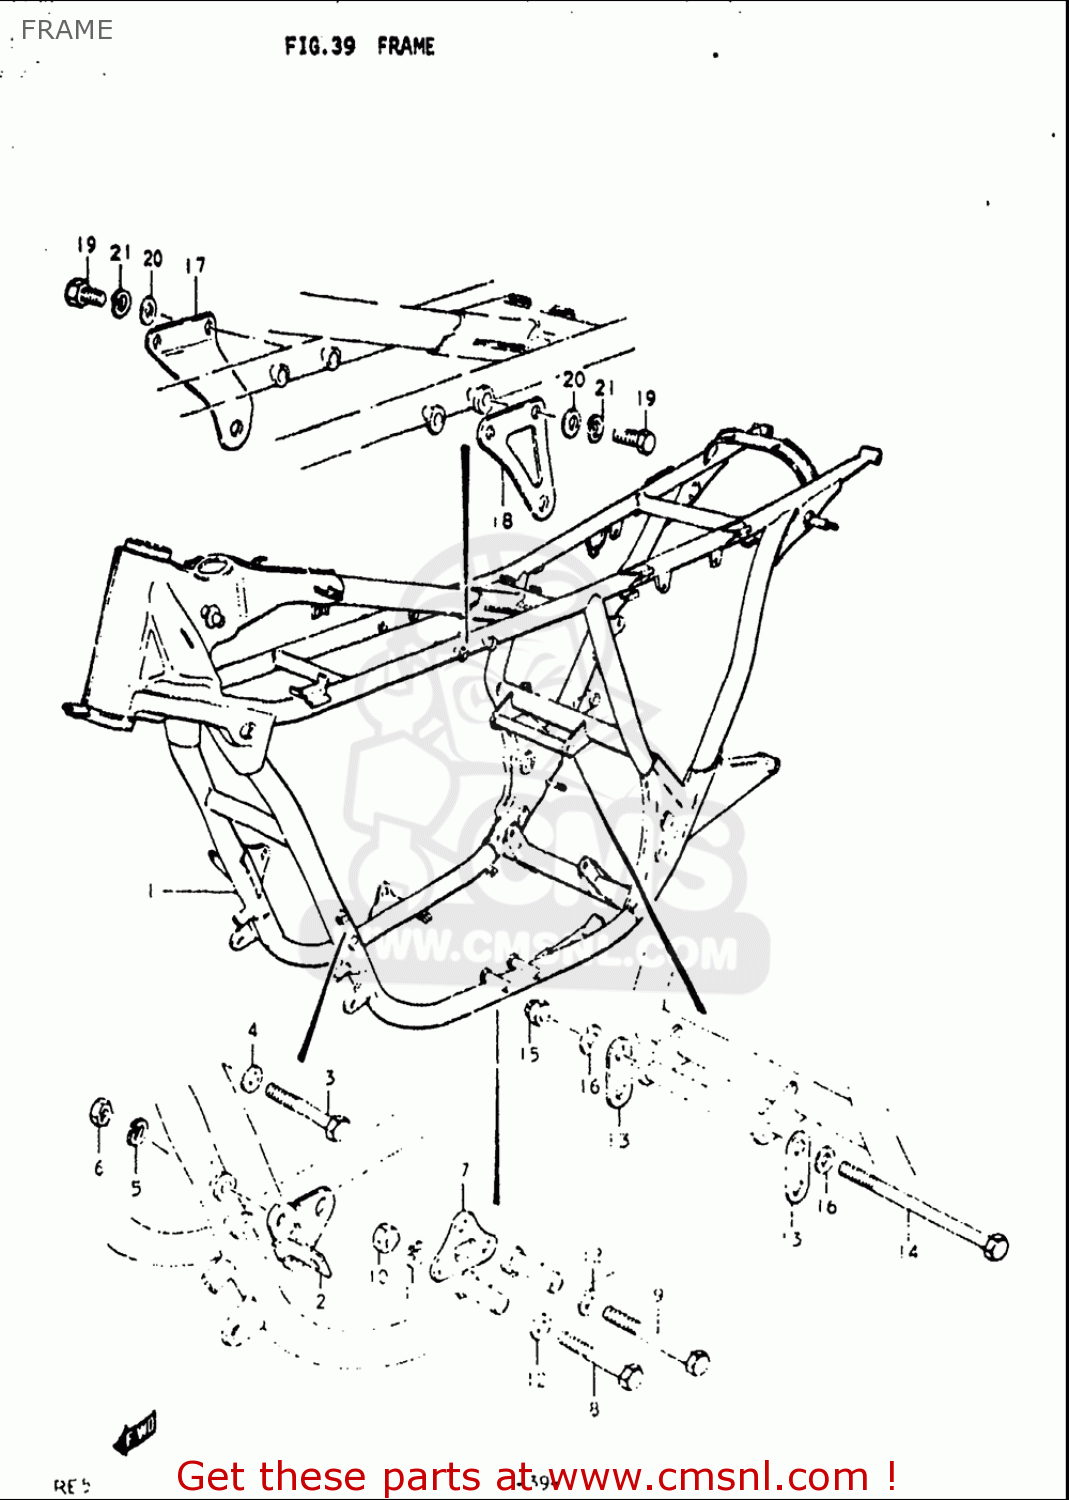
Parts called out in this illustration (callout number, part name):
3	BOLT
4	WASHER
5	WASHER,LOCK
6	NUT
8	BOLT
9	BOLT
10	NUT
11	WASHER,LOCK
12	WASHER
14	BOLT
15	NUT
16	WASHER
19	BOLT
20	WASHER
21	WASHER,LOCK
